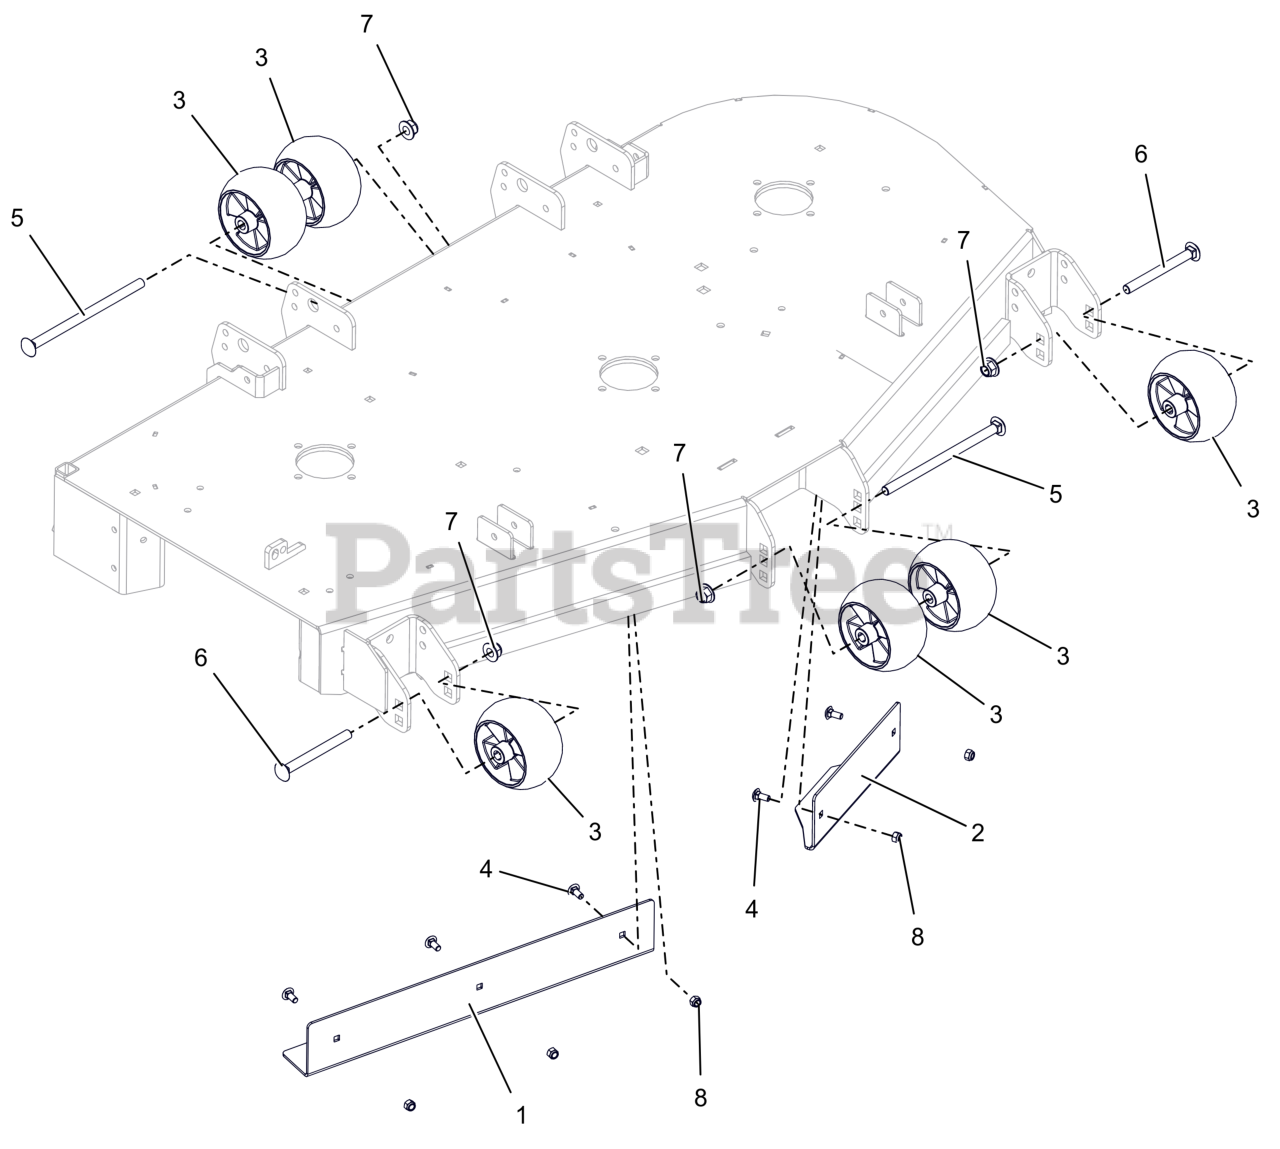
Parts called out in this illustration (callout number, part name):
1	BAFFLE, 52" RH VACUUM (RED)
2	BAFFLE, 52" LH VACUUM (RED)
3	WHEEL, ANTI SCALP - 5X3 CTR W/RIBS
4	BLT,RHSN .31-18X.75 G5 ZCC
5	BTL,RHSN .500-13 X 8.5S G5 ZCC
6	BLT, RHSN .50-13X5.00 G5 ZCC
7	NUT,NYL-FLG .50-13 GF ZCC
8	NUT,NYL .31-18 G5 ZCC
